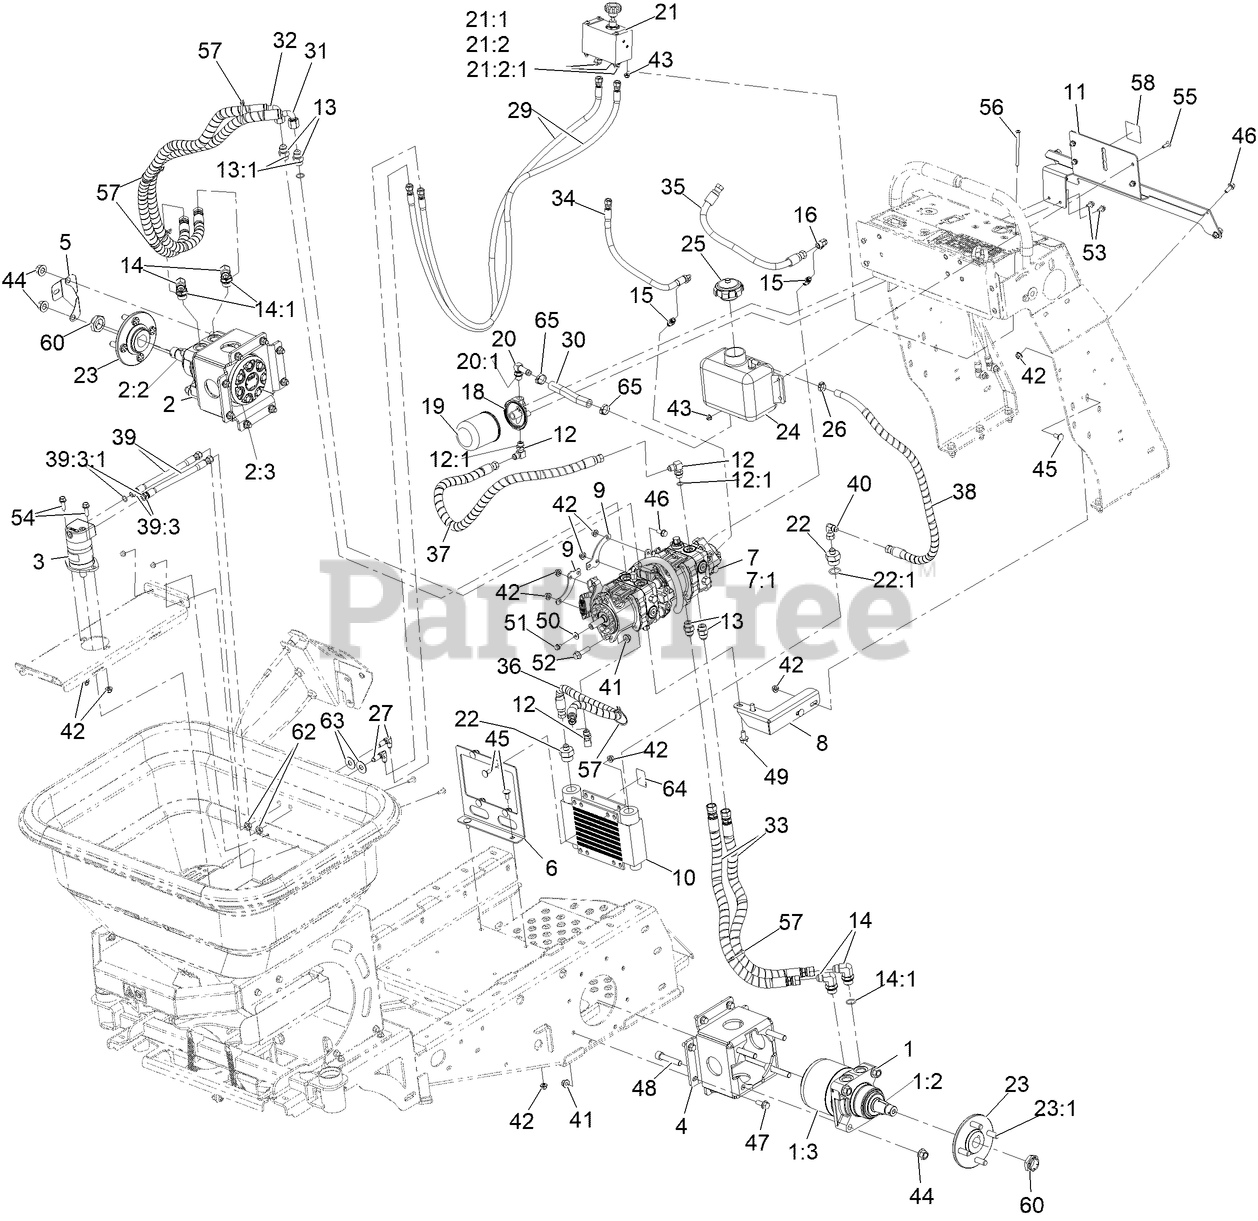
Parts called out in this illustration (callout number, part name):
1	MOTOR, LH WHEEL
1:2	KEY-WOODRUFF
1:3	SEAL KIT
2	MOTOR, RH WHEEL
2:2	KEY-WOODRUFF
2:3	SEAL KIT
3	MOTOR-HYDRAULIC, SPREADER
4	Mount-Motor, Wheel [black]
5	BRACKET-HOPPER, SPEEDOMET
6	Mount-Cooler
7	PUMP-TANDEM
7:1	ASM-AUX PUMP -73054
8	Bracket-Support, Hydro Pump
9	Extension, Hydro Pump
10	COOLER-OIL
11	Mount, Hydraulic Tank And Filter
12	FITTING-ELBOW, 90 DEG
12:1	O-RING
13	FITTING-STRAIGHT
13:1	O-RING
14	FITTING-90 DEG
14:1	O-RING
15	FITTING-STRAIGHT
16	FITTING-90 SWIVEL
18	HEAD-FILTER
19	FILTER-25 MICRON, BI-DIRECTIONAL
20	FITTING-ELBOW, 90
20:1	O-RING
21	Manifold-Flow Control, Hopper
21:2	FITTING-ELBOW, 45 DEG
21:2:1	O-RING
22	ADAPTER-STRAIGHT
22:1	O-RING
23	HUB-WHEEL
23:1	STUD-1/2-20 X 1.55
24	TANK-HYDRAULIC, PLASTIC
25	Cap-Vented
26	CLAMP-OETIKER, 167
27	FITTING-ELBOW, 90
29	Hose ASM, HYD HP
30	HOSE-HYDRAULIC
31	HOSE ASM-HYD HP
32	Hose ASM-HYD HP
33	Hose ASM-HYD HP
34	Hose ASM-HYD HP
35	Hose ASM, HYD LP
36	Hose ASM, HYD LP
37	Hose ASM, HYD LP
38	Hose ASM, HYD LP
39	Hose ASM-HYD HP
39:3	Fitting-Straight, Rigid
39:3:1	O-RING
40	ELBOW-SWIVEL, 90 DEG
41	Nut-Hex Flange
42	Nut-Hex Flange
43	Nut-Hex Flange
44	Nut-Lock 1/2-13
45	SCREW-CARR
46	SCREW-HHF
47	SCREW-HHF
48	Screw-HSH
49	SCREW-HHF
51	SCREW-HHF
52	SCREW-HHF
53	SCREW-HHF
54	SCREW-HHF
55	Screw-Hsbhf
56	Screw-HSBH
57	TIE-CABLE
58	DECAL-OIL
60	LOCKNUT
62	Nut-Jam
63	Washer-SS, 1.25 OD, .503 ID
64	DECAL-WARNING
65	CLAMP-OETIKER, 167
